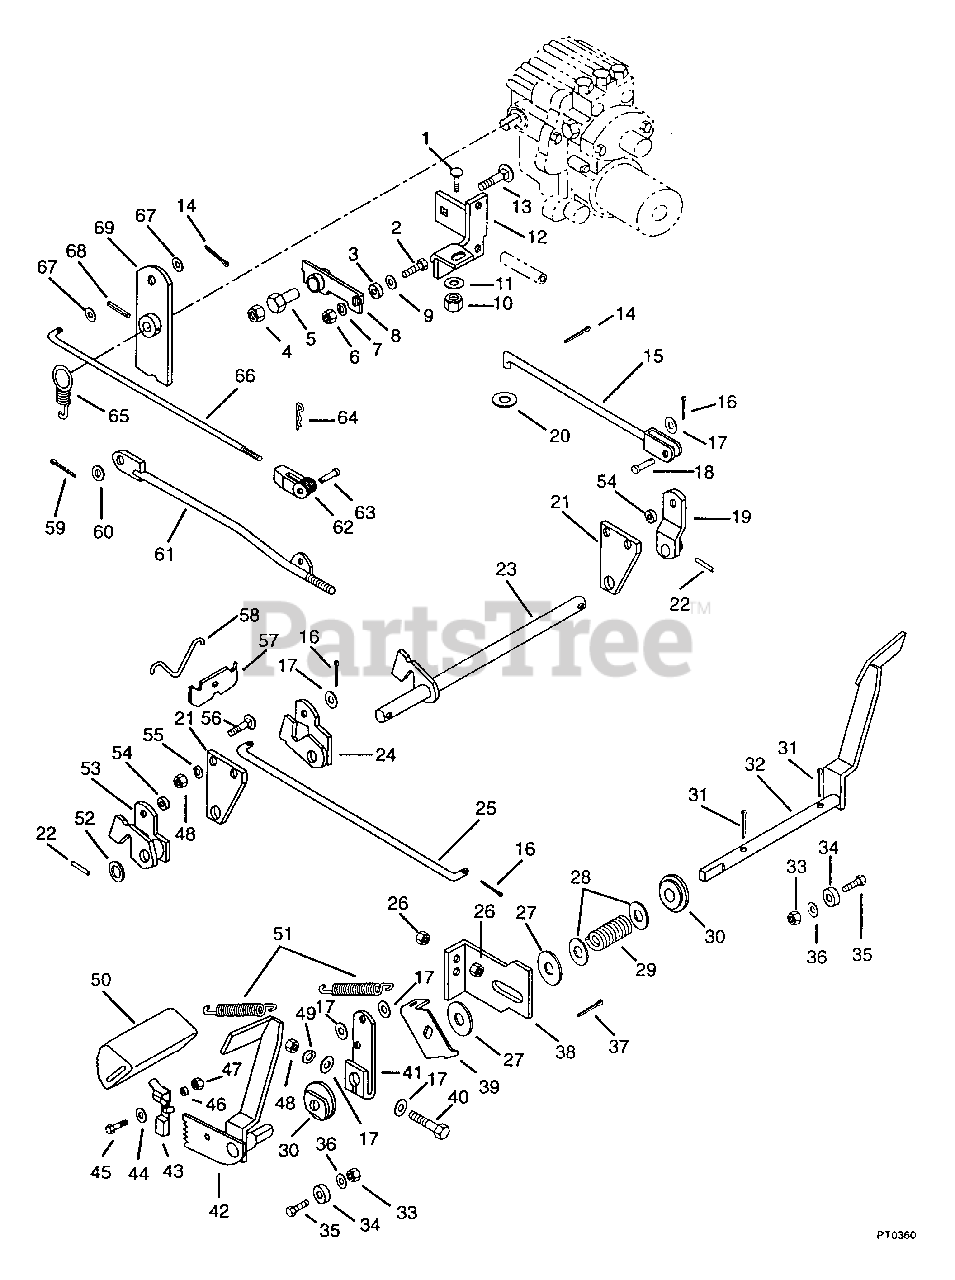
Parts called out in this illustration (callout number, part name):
1	BLT-RDHDSQNK .50-13X1.25GR5PL
2	BLT-HEX .25-20X1.00 GR2
3	BRG BALL DBL .250X.638X.438
4	NUT-LK-NYL.312-18 PL
5	ECCENTRIC
6	NUT-LK-CTR .250-20 PL
7	WSHR-LK .250X.047 LT PL
8	DETENT ARM
9	WSHR-FL-STL .281X1.250X.048PL
10	NUT-LK-CROWN .50-13 GR C PL
11	WSHR-FL-STL .531X1.062X.095 PL
12	MOUNT WELDMENT
13	BLT-RDHDSQNK.31-18X2.25 PL
14	PIN-COTR .09X.75 PL
15	BRAKE ROD
16	PIN-COTR .12X.75 PL
17	WSHR-FL-STL.406X.812X.065PL
18	PIN-CLEV .373X1.12 YWZC
19	BRAKE ARM
20	WSHR-FL-STL .382X.812X.023 PL
22	PIN-GRV .250X1.25 TP A
23	BRAKE SHAFT
25	BRAKE ROD
26	NUT-LK-CTR .50-13
27	WSHR-FL-STL .755X2.000X.125
28	WSHR-FL-STL .755X1.375X.062 PL
29	SG-COMP .148X1.23X2.53 WLD87
30	BSHG-FLG .750X1.750X.875X2.125
31	PIN-COTR .18X1.25 PL
32	L H LEVER
33	NUT-LK .312-18 GR A PL
34	SPACER .344X1.000X.375
35	BLT-HEX .31-18X.88 PL GR2
36	WSHR-FL-STL .38X.875X.083 PL
37	PIN-COTR .09X1.0 PL
38	NEUTRALIZER PLATE
39	NEUTRALIZER ARM
40	BLT-HEX .38-16X2.25 GR2
41	ARM-BRAKE
42	R H LEVER
43	BRAKE LATCH
44	WSHR-FL-STL.281X.62X.065 PL
45	BLT-HEX .25-20X.75 PL GR2
46	SPACER BUSHING .37 X .26 X .14
47	NUT-LK-CTR .250-20 PL
48	NUT-HEX .375-16
49	WSHR-LK .375X.094 MED PL
50	PEDAL COVER
51	SG-TENS .090X.75X3.50 WLD 34
52	WSHR-FL-STL .754X1.125X.062 PL
53	BRAKE ARM
54	GROMMET
55	WSHR-LK .375X.115 HVY PL
56	BLT-RDHDSQSHNK .38-16X1.00 PL
57	BALANCE LINK
59	PIN-COTR .12X1.0 PL
60	WSHR-FL-STL .531X1.062X.095 PL
61	NEUTRALIZER ROD
62	YOKE, .312-24 X 2.25
63	PIN-CLEV .312X.822 HDND PL
64	PIN-HAIR INT .08X.18X1.18
65	SG-TENS .080X.75X2.81 WLD 20
66	SHIFT ROD
67	WSHR-FL-STL .323X.625X.062 PL
68	PIN-ROLL .250X1.38
69	SHIFT ARM
